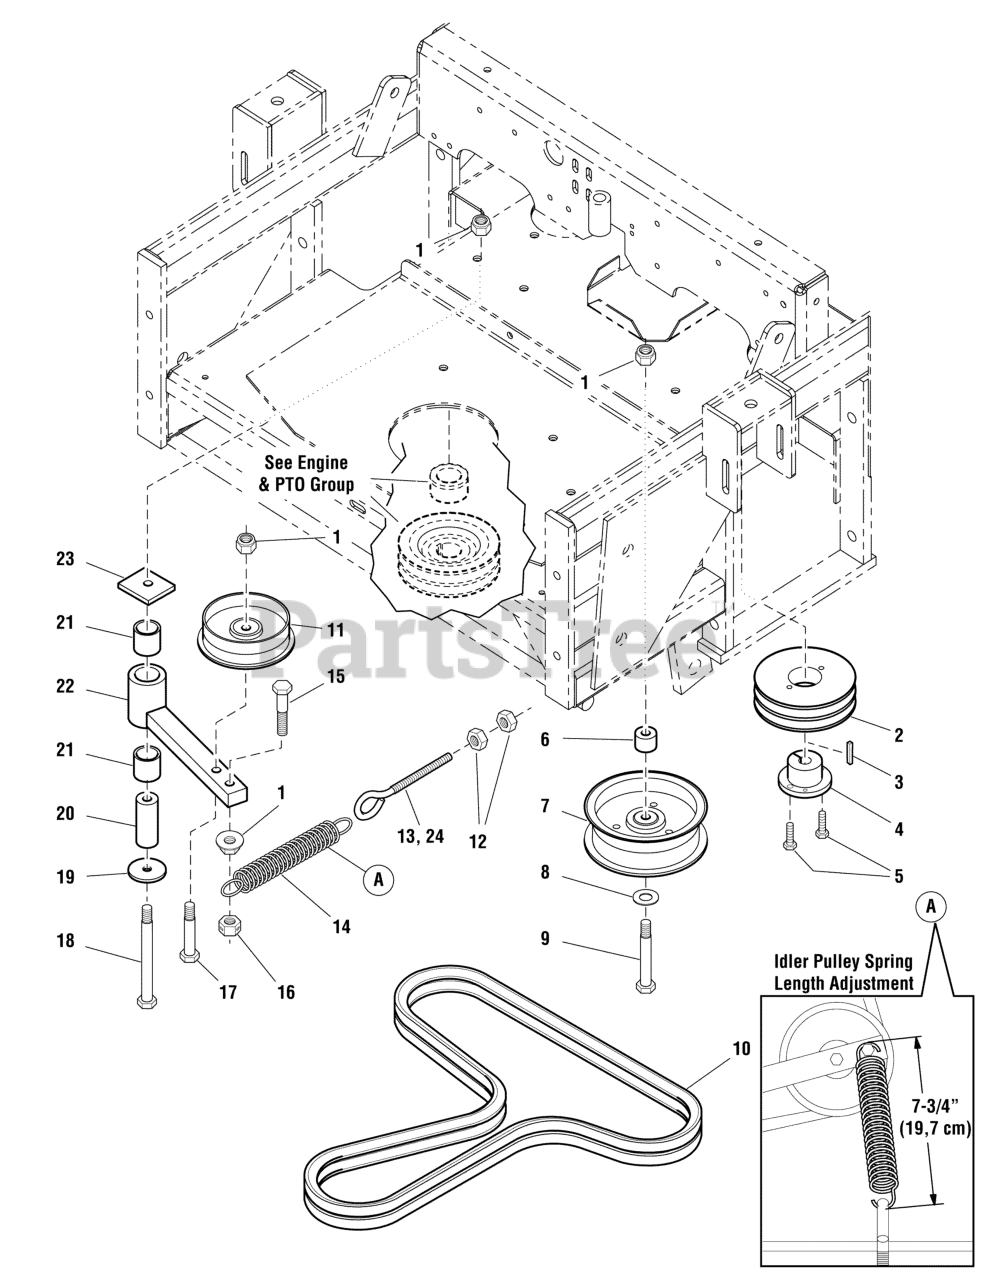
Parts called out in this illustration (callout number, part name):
1	NUT, 3/8 - 16 HEX NYLOCK FLANGE
2	PULLEY, 5.45 OD, DOUBLE GROOVE
3	KEY, 5 MM SQ X 25 MM LONG
4	BUSHING, 17MM, HQ
5	BOLT, 1/4-20 X 1" GD5 CZ
6	SPACER, .39 X 1.00 X .80
7	PULLEY, IDLER 5"
8	WASHER, 3/8 SAE
9	BOLT, 3/8-16 X 2-1/4" GD5 CZ
10	BELT, A-SEC, 69.5EL, POLYESTER, RAW EDGE
11	PULLEY, IDLER, SINGLE FLANGE
12	NUT, 3/8-16 HEX
13	EYE BOLT, 3/8-16 X6", 1" EYE
14	SPRING, EXTENSION, SWIVEL END
15	BOLT, 3/8-16 X 1-3/4" GD5 CZ
16	NUT, 3/8-16 HEX SIDE LOCK
17	BOLT, 3/8-16 X 2-1/4" GD5 CZ
18	BOLT, 3/8-16 X 4" GD5 CZ
19	WASHER, .41 X 1.75 X .14
20	SPACER, .39 X 1.00 X 2.55, SS
21	BUSHING, BRASS, 1.25X1.0X1.25
22	WELD, ARM, PUMP DRIVE IDLER - BLK
23	SPACER, IDLER PIVOT
24	EYE BOLT, 3/8-16 X 6.88, 3THRD, 1EYE
